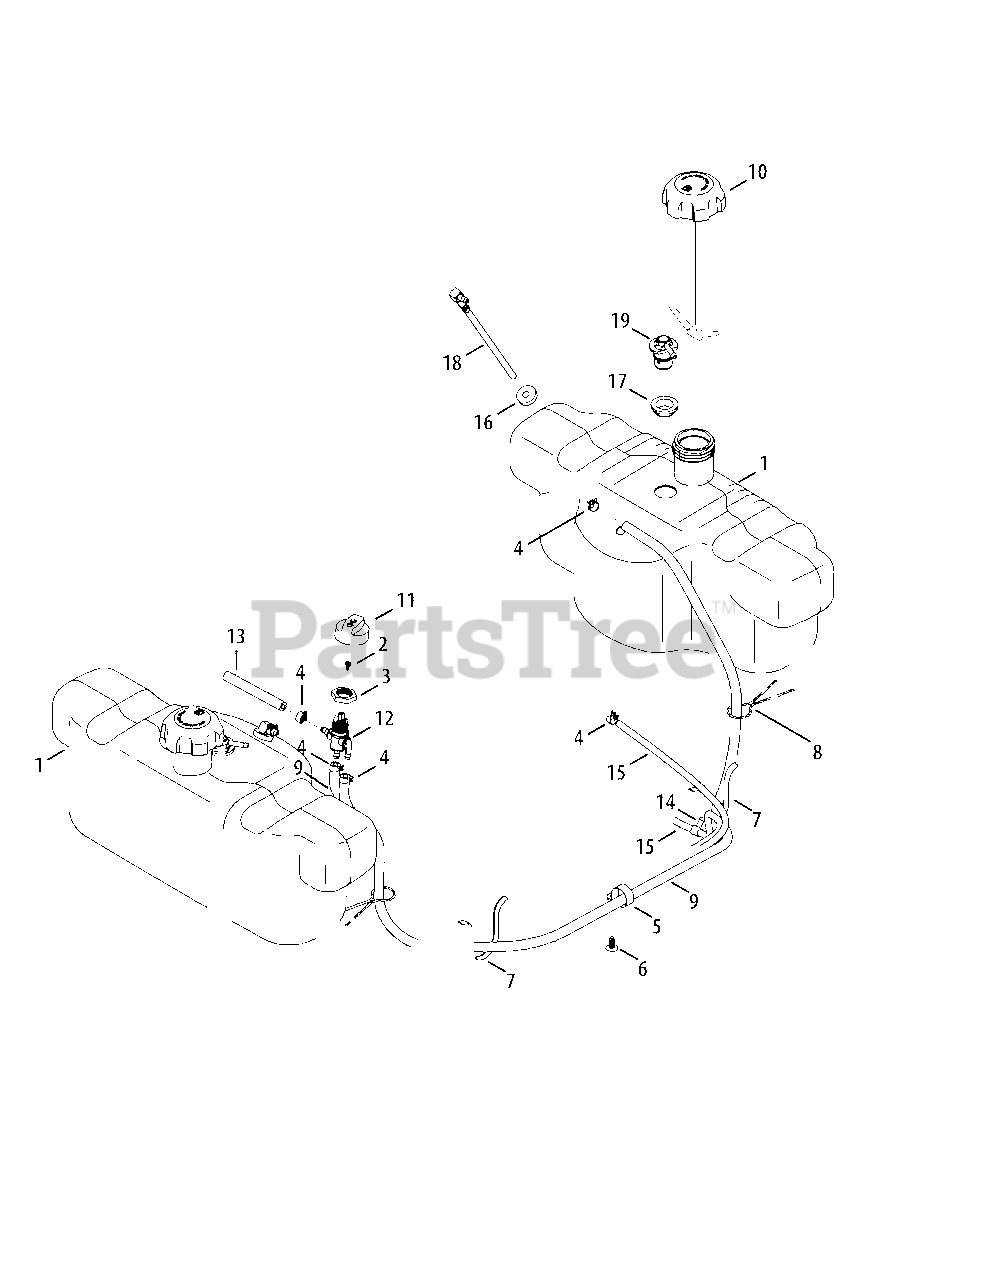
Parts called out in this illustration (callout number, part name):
1	Fuel Tank
2	Screw, M4-0.7 x 8mm
3	Nut, 3 Way Select
4	Hose Clamp, .490 Dia.
5	Hose Clamp, 1.0
6	Ratchet Clip, .250
7	Trim Strip
8	Tank Support Rod
9	Fuel Hose, Low Permeation, 1/4
10	Fuel Cap
11	Fuel Cap, 3 Way
12	Fuel Switch
13	Fuel Hose, Low Permeation, 1/4
14	Tee Fitting
16	Fuel Tank Bushing
17	Rubber Grommet
18	Fuel Pickup Fitting
19	Rollover Valve
